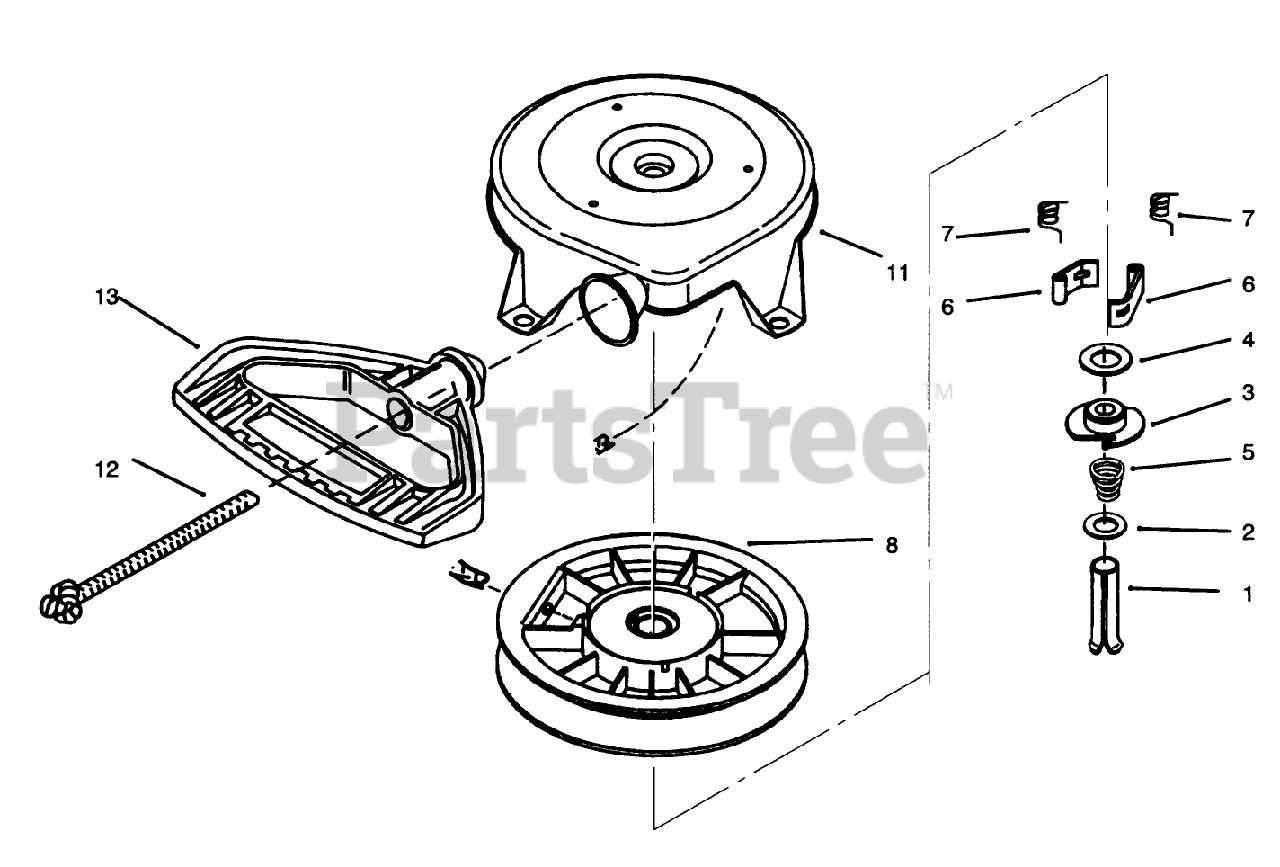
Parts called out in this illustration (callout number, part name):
1	Pin, Spring (Incl. Ref. #7)
2	Washer
3	Retainer
4	Washer
5	Spring-Brake
6	Dog-Starter
7	Spring-Dog
8	Pulley and Rewind Spring ASM
11	Housing Assy.-Starter
12	Rope-Starter
13	Handle-Starter, Mitten Grip
